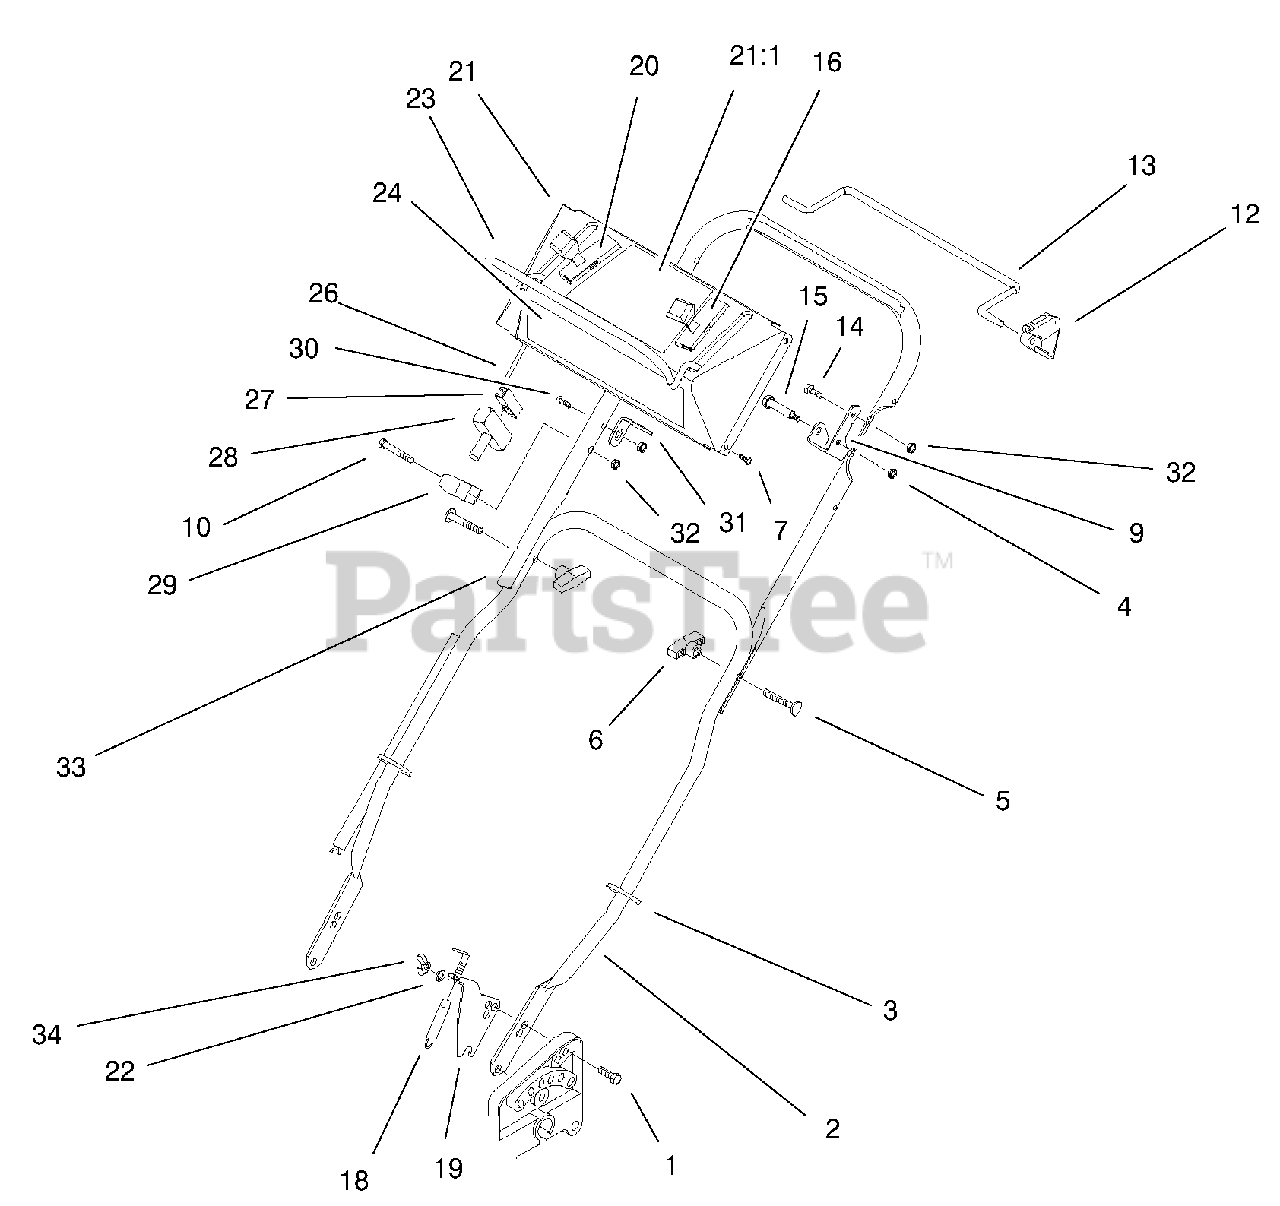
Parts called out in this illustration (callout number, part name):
1	Bolt-CARR
2	Handle-Lower
3	Tie Strap
4	Nut-Lock
5	Screw-Handle
9	Bracket-Stop, Bail
10	Bolt-HH
12	Stop-Pivot
13	Bail-Control
14	Screw-HH
16	Control ASM-Throttle
18	Cable-Traction
19	Bracket-Traction Cable
20	Cable-Ground Speed
21	Control Panel ASM
21:1	Decal-Control Panel
22	Washer-Lock
23	Bail-Engine Control
24	Decal-Panel
26	Brake Cable ASM
27	Starter-Clip
28	Handle-Start
29	Guide-Rope
30	Screw-Handle
31	Bracket-Anchor, Cable
32	Nut-Lock
33	Handle-Upper
